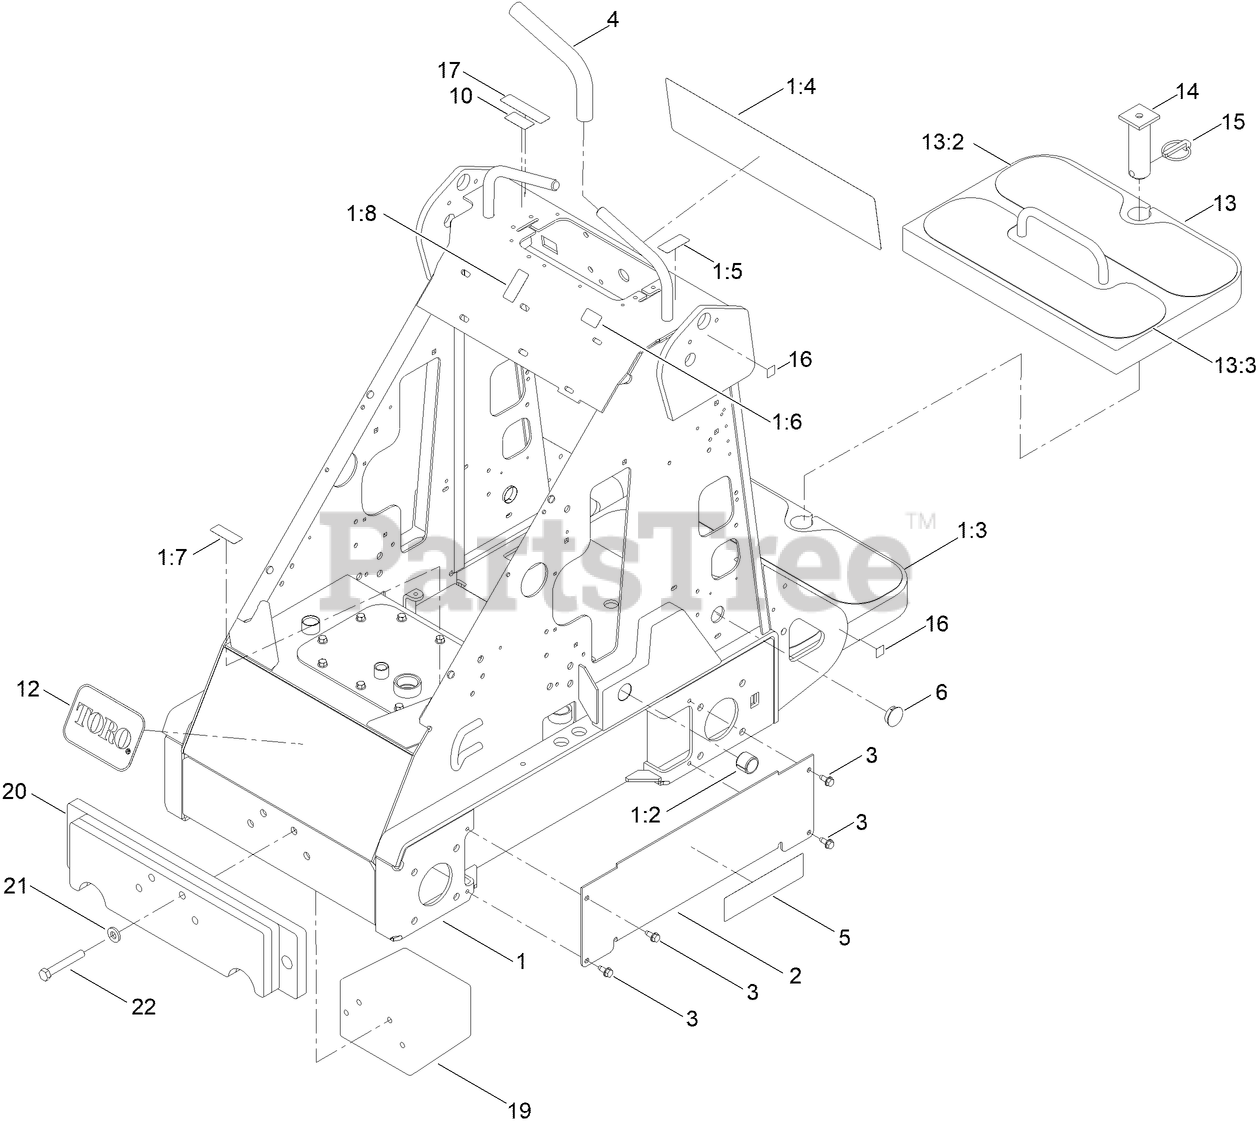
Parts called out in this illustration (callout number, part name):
1	FRAME ASM
1:2	BUSHING-TENSION
1:3	TREAD-FOOT
1:4	DECAL-CONTROL PANEL, CE
1:5	DECAL-THROTTLE
1:6	DECAL-LIMITER, SPEED
1:7	DECAL-OIL, HYD
1:8	DECAL-SELECTOR
2	COVER-HOSE
3	SCREW-HWHTF
4	GRIP-CUSHION
6	PLUG-HOLE
10	DECAL-PROTECTION, EAR
12	DECAL
13	COUNTERWEIGHT ASM
13:2	TREAD-FOOT
15	PIN-LYNCH
16	DECAL-POINT, LIFT
17	DECAL-ARRESTOR, SPARK
19	WEIGHT-FRONT, COUNTER
20	WEIGHT-COUNTER [BLACK]
21	WASHER
22	SCREW-HH
